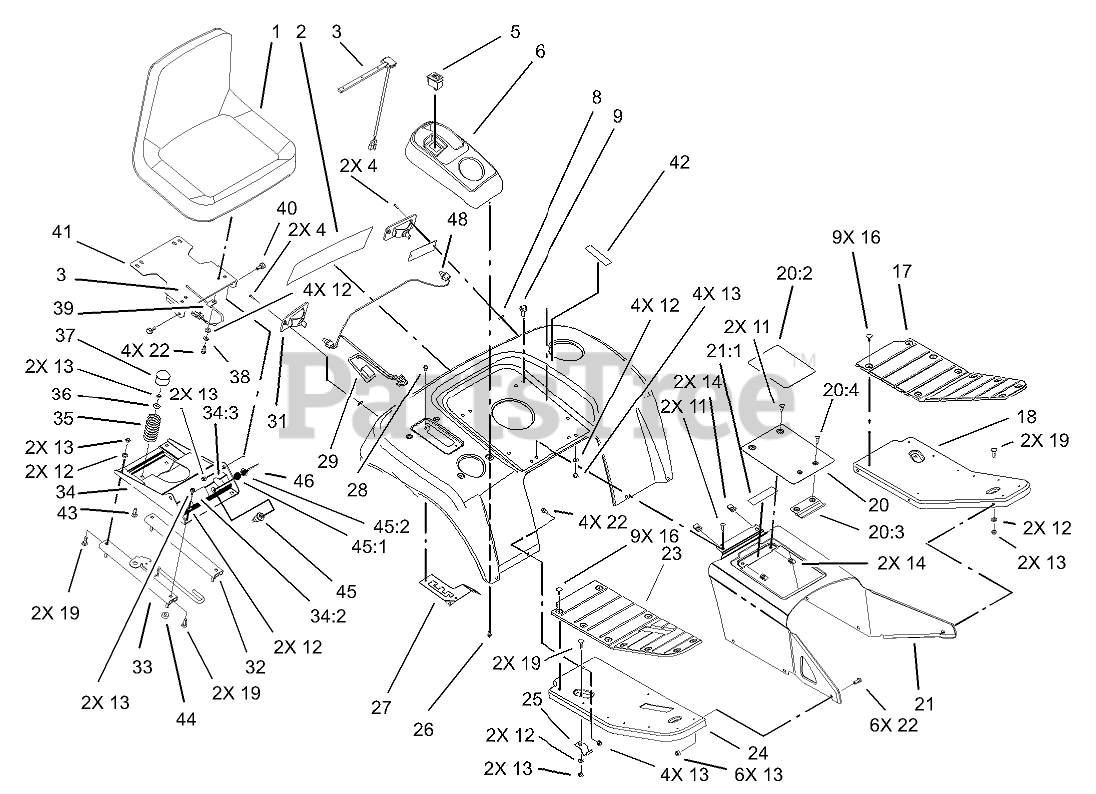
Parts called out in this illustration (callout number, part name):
1	SEAT
2	Decal-Rear Fender
3	SWITCH-SEAT
4	SCREW-PPH
5	SWITCH-CRUISE
6	POD - CONTROL INT'L
8	NUT-SPEED
9	SCREW-HHF
11	SCREW-HH
12	WASHER-PLAIN
13	NUT-LOCK, NI
16	FASTENER-PANEL
17	PAD-FOOTREST, LH
18	FOOTREST-LH
19	SCREW-CARR
20	TUNNEL COVER ASM
20:2	DECAL - DANGER
20:3	RETAINER-COVER
20:4	SCREW-PPH
21	TUNNEL ASM
21:1	DECAL - WARNING
22	SCREW-HH
23	PAD-FOOTREST, RH
24	FOOTREST-RH
25	BRACKET-FOOTREST
26	SCREW-HHFTF
27	GATE-HI / LO SHIFT
28	SCREW-HWH
29	HARNESS-REAR
31	LAMP-TAILLIGHT
32	SLIDE-SLAVE, SEAT
33	SLIDE-LATCH, SEAT
34	Seat Base ASM, Intl Decal (only on: 73570)
34:2	DECAL-DANGER
34:3	DECAL-SWITCH
35	SPRING-COMPRESSION
36	BUSHING
37	CAP-SPRING, SEAT
38	WASHER-LOCK
39	CLAMP-R
40	BOLT-SHOULDER
41	MOUNT-SEAT
42	DECAL - DIESEL
43	SCREW-CARR
44	WASHER-FLAT
45	STARTER SWITCH ASM
45:1	WASHER-TOOTH, INTERNAL
45:2	NUT-HH
46	KEY-IGNITION
48	LIGHT BULB
